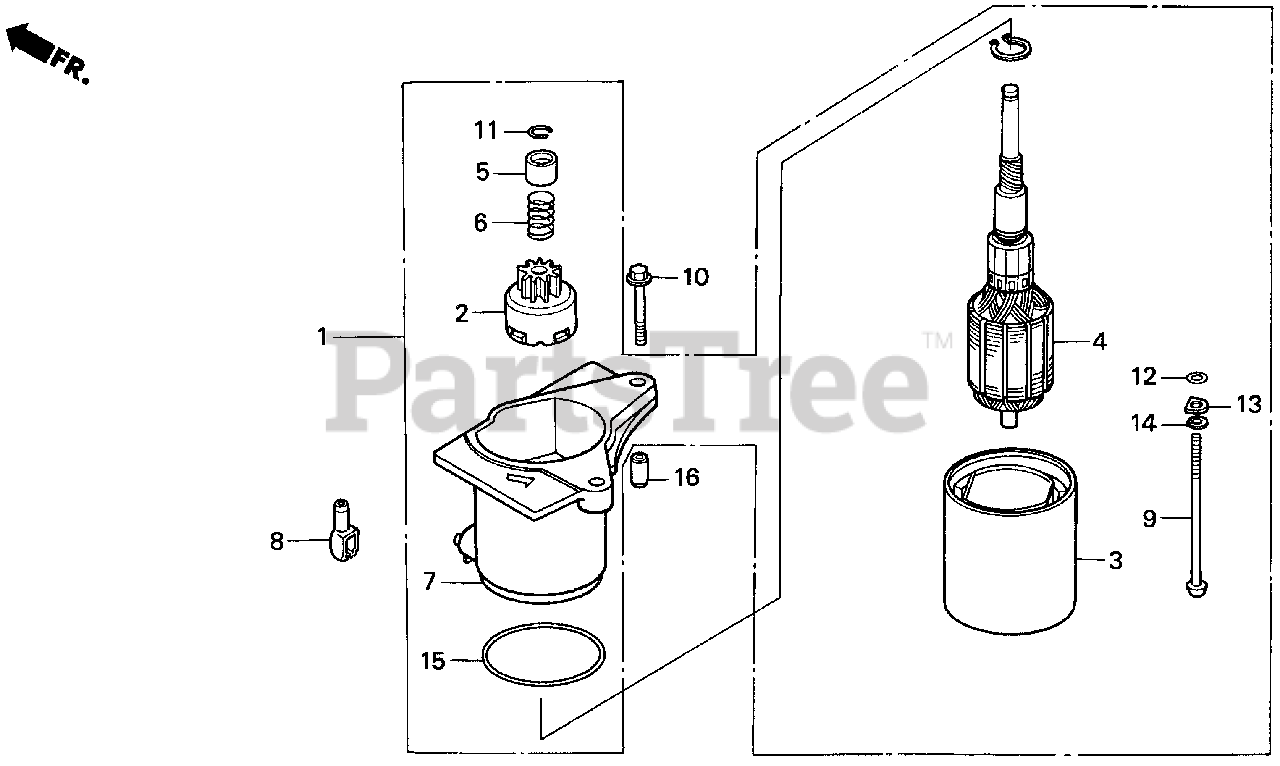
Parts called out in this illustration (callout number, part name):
1	MOTOR UNIT, STARTER
2	GEAR ASSY., PINION
3	YOKE ASSY.
4	ROTOR ASSY.
5	PIECE, STOPPER
6	SPRING, RETURN
7	BRACKET, FR.
8	COVER, TERMINAL
9	BOLT, SETTING
10	BOLT, FLANGE (6X32)
11	CIRCLIP (OUTER) (8.3MM)
12	O-RING
13	WASHER, SPECIAL
14	WASHER, SPRING
15	O-RING
16	PIN A, DOWEL (8X14)
